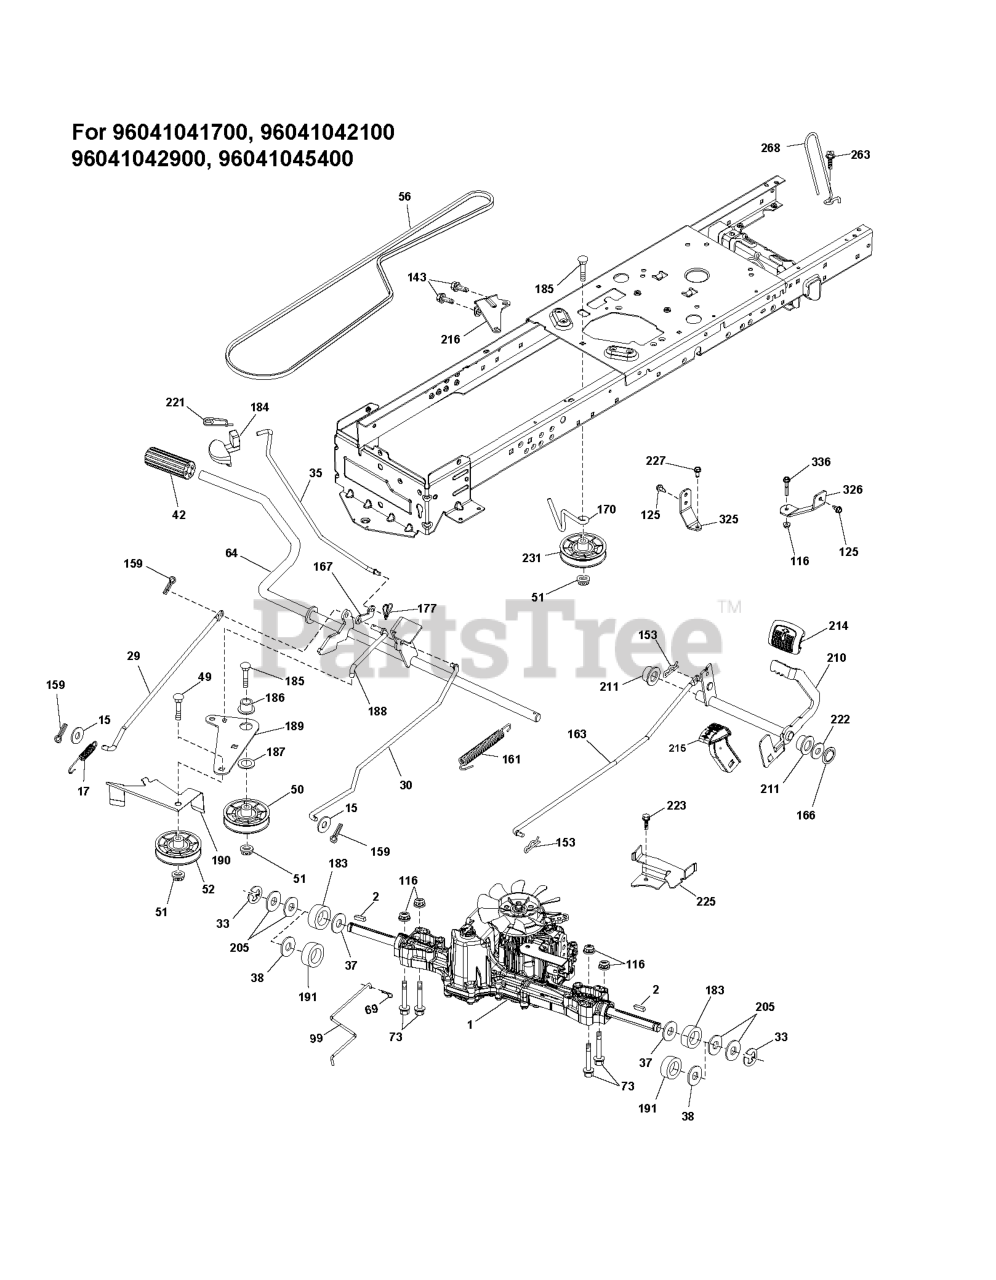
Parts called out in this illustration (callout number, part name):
1	TRANSAXLE(K46BT).PDL.
2	SQUARE KEY
15	WASHER
15	WASHER PLAIN WASHER 3/8 X 0.08
17	SPRING.BRAKE.K46.GREEN
29	ROD.BRAKE.K46
30	ROD.BRAKE.K46
37	WASHER.HARDENED
38	WASHER.HARDENED
42	PEDAL COVER
50	IDLER.FLAT.910.OFFSET
51	NUT LOCK FLG 3/8-16 UNC
52	IDLER.V-GROOVE.910.OFFSET
64	SHAFT.ASM.PEDAL.BRK.CNTR
69	HAIRPIN.SOFT.ZINC.059X1.125
99	ARM.PIVOTING.TCRD.GEN2.5.BAGGE
125	SCREW
153	RETAINER M
161	SPRING, RETURN LT
166	NUT.PUSH.625
167	LATCH.BRAKE.SPRING
170	KEEPER.CENTER SPAN.1.688
177	PIN COTTER;LOCKING;BOWTIE;1IN
177	GSPW Retainers
183	SPACER AXLE
184	HANDLE.PARKNG BRK.PRED.LT.428
186	SPACER.RETAINER
188	LINK.CLUTCH.GROUND DRIVE.LONG
189	BELLCRANK.GROUND.DRIVE.TEX.
190	KEEPER.BELLCRANK.DRIVE
191	SPACER AXLE
210	ROCKER.ASM.PEDAL.CONTR
211	BEARING.NYLON
214	PEDAL.FORWARD.PAD.TEX
215	PEDAL.COVER.REVERSE.CRD.X428BK
216	BRACKET.PULLEY.IDLER.W/TEX
221	RETAINER.SPRING.CLIP.H
222	WASHER 21/32 X 1-1/4 X 10 GA.
225	KEEPER.BELT.TRANSAXLE.K46
231	IDLER.V-GROOVE.1.688.OFFSET
263	SCREW, 3/8-16X3/4
268	Mufflers
325	TORQUE.STRAP.K46.LT.LH
326	BRCKT.PNT.TRQ.STP.46.18TIRE.RH
